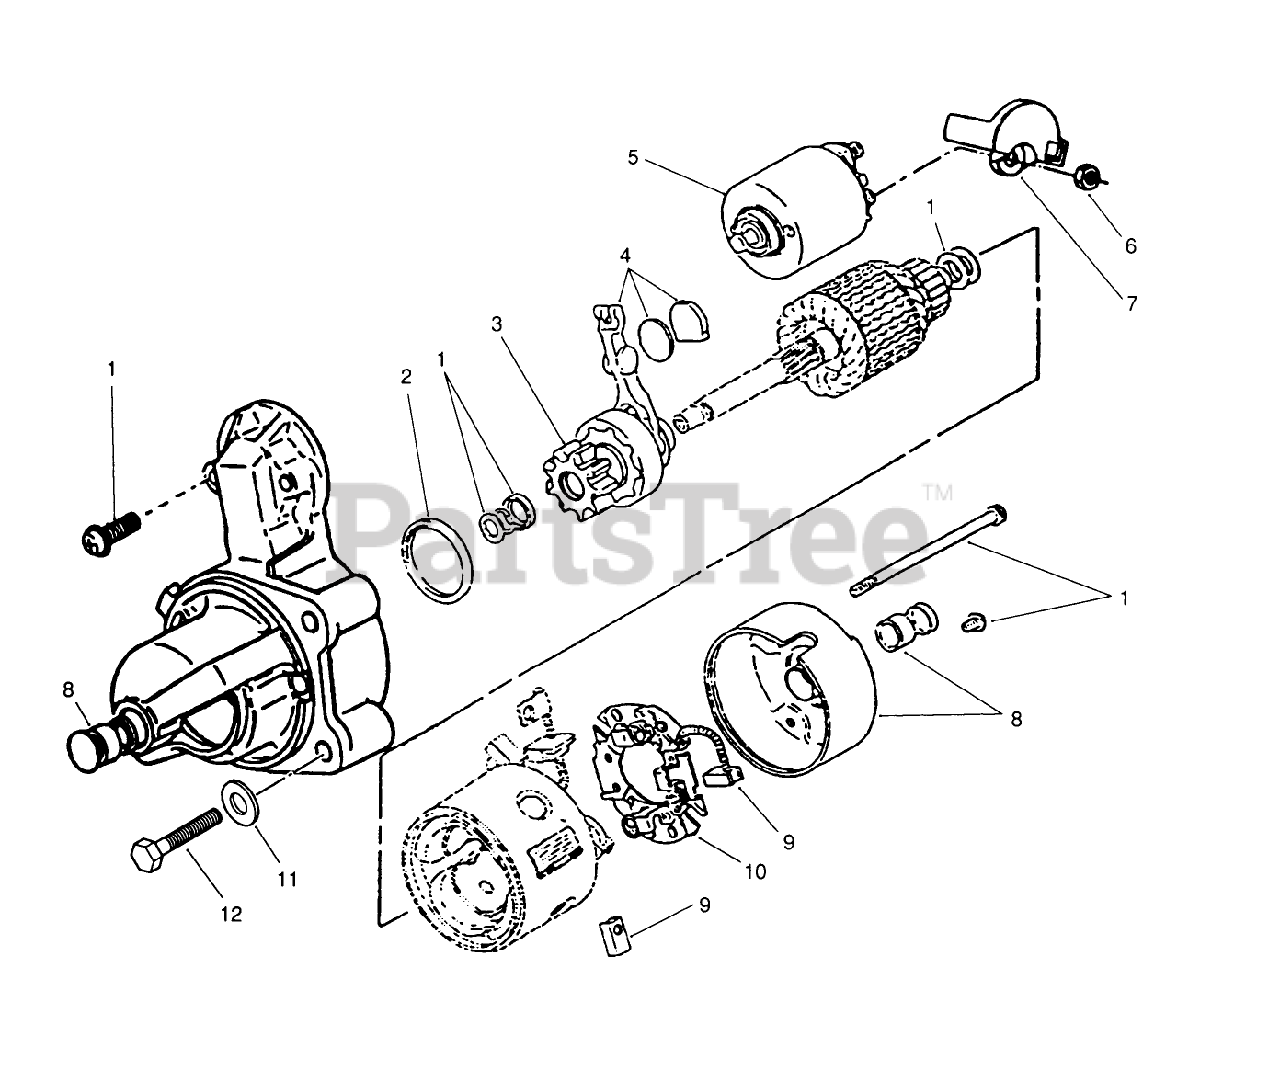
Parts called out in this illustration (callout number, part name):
8	BUSHING
10	Holder-Brush, Starter
13	KIT-MTG BRKT
14	WASHER
